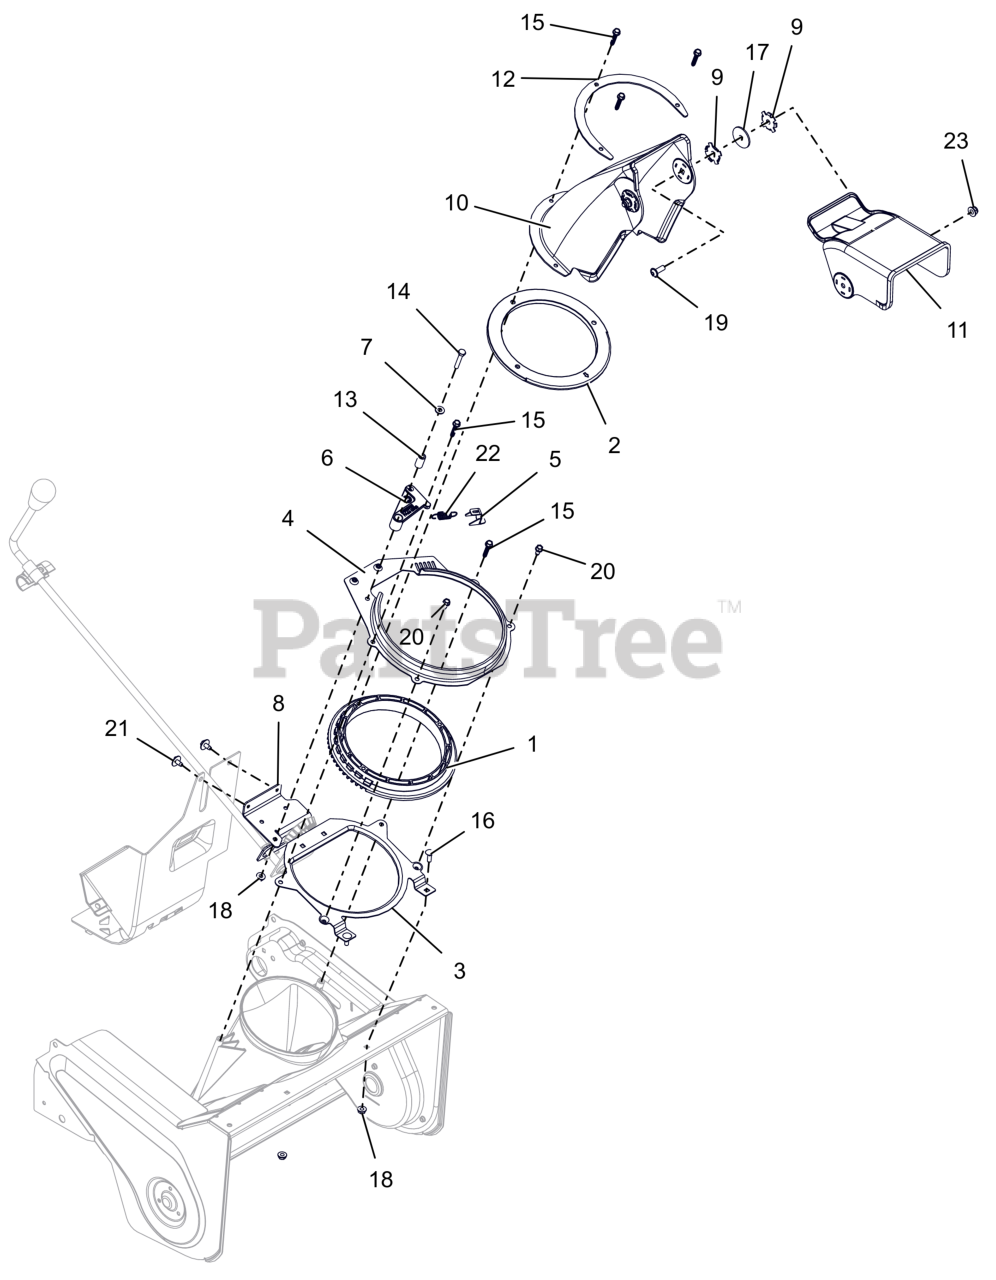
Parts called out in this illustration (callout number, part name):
1	GEAR, CHUTE RING
2	GUARD, WATER
3	RING, CHUTE MOUNT - LOWER
4	RING, CHUTE MOUNT - UPPER
5	BRKT, SPRG
6	ARM, PAWL
7	WSHR,FLT .281X.625X.065 ZCC
8	BRKT, CHUTE ROTATION - REAR
9	PLATE, FRICTION
10	CHUTE, DISCHARGE-SINGLE STAGE
11	CAP, CHUTE-SINGLE STAGE
12	BRKT, ROTATION - MANUAL
13	BSHG, SLV .265X.505X.995
14	BLT, HEX .25-20X1.50 G5 ZCC
15	SCR,PLASTITE .25-10X1.25 ZCC
16	BLT, RHSN .25-20X.750 G5 ZCC
17	WSHR,FRICTION-.332X1.525X.094
18	NUT-LK-TOP-FLG .250-20 GF ZCC
19	SCR,BTN-FLG .31-18X0.875
20	SCR-TAP .25-20X.50 HWH ZCC
21	SCR, TAP .25-20X.50 LG HWH ZCC
22	SPRG, TENSION .052X.520X1.74
23	NUT,LK-NYL-FLG .31-18 G5ZC120
